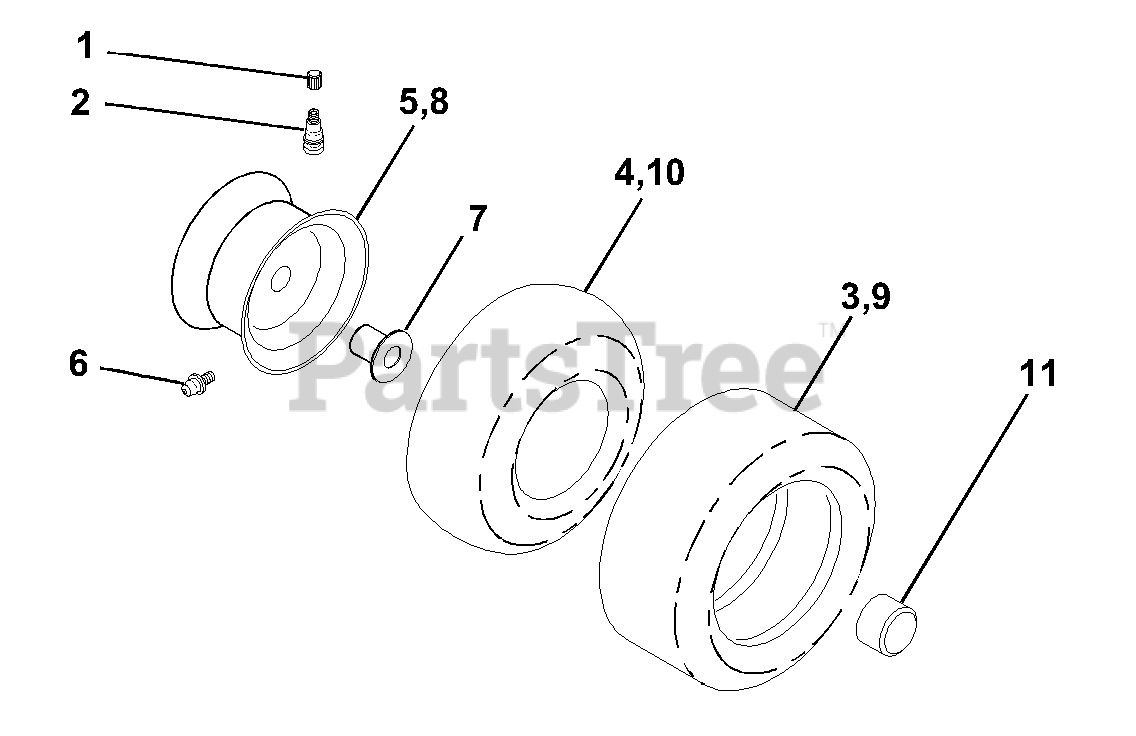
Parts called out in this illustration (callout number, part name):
1	Cap Valve Tire
2	Stem Valve
3	Tire F Ts 15 X 6 0 - 6 Service
4	Tube
5	Rim Asm 6" front Service
6	Fitting Grease
7	Bearing Flange
8	Rim Asm 8" rear Service
9	Tire R Ts 18x9.5-8 C Service
10	Tube Rear
11	Cap Axle Blk 1 50 X 1 00
